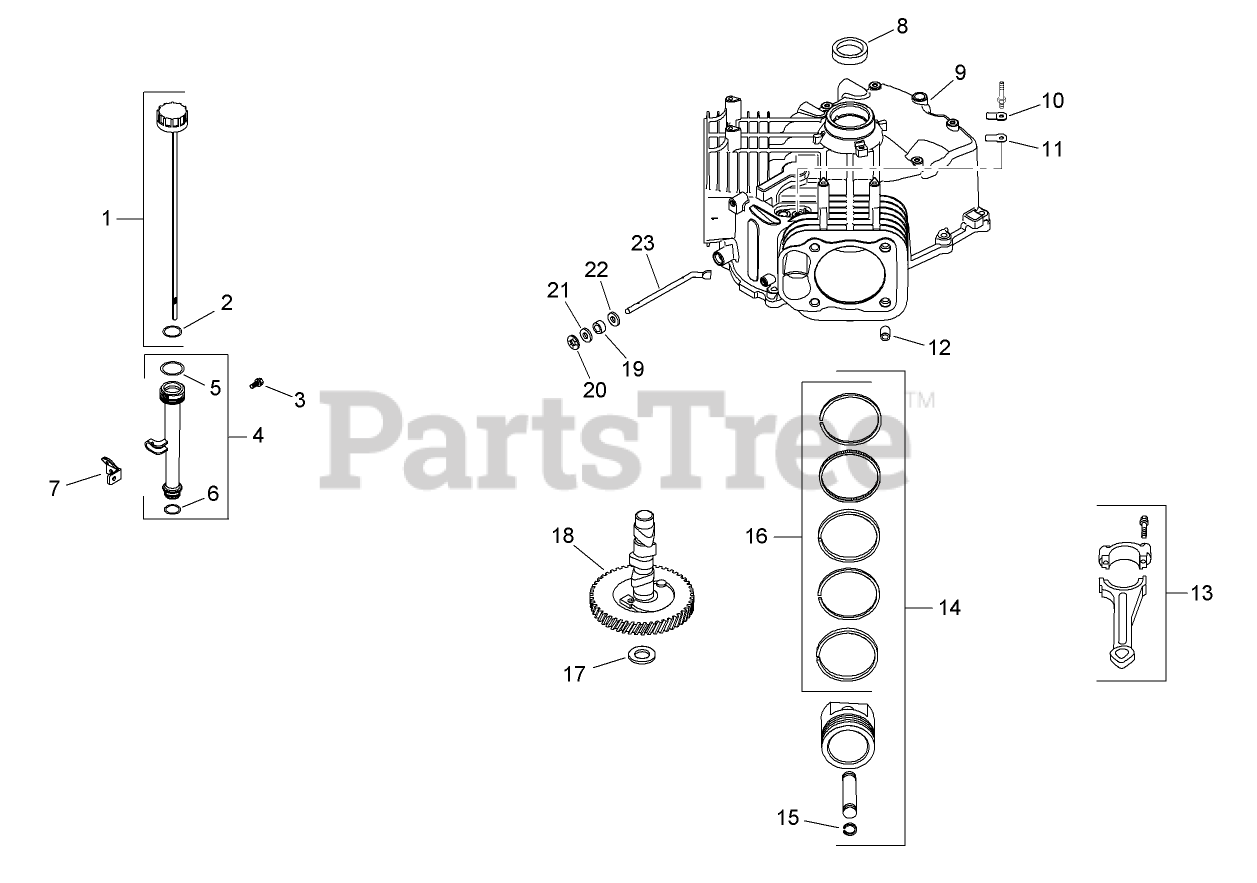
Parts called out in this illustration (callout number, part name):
1	Dipstick Kit (Includes?2)
2	O RING-DIPSTICK
3	SCREW-FLG, THD FRM (M5X0.8X13)
4	OIL FILL TUBE KIT
5	O-Ring
6	O-RING
7	BRACKET-TUBE, OIL FILL
8	SEAL-OIL
9	SHORTBLOCK (SV710-740)
10	RETAINER-REED, BREATHER
11	REED-BREATHER
12	PIN-LOCATING
13	ROD-CONNECTING (STD)
14	PISTON W/RING SET (STD) (INCLUDES REF 8, 17)
14	PISTON W/RING SET (.25)
14	PISTON W/RING SET (.08) (USE 25 874 02-S KIT)
15	RETAINER-PIN, PISTON
16	PISTON RING SET (STD)
16	PISTON RING SET (.25)
17	SHIM-CAMSHAFT (WHITE .028)
17	SHIM-CAMSHAFT (BLUE .03)
17	SHIM-CAMSHAFT (RED .032)
17	SHIM-CAMSHAFT (YELLOW .034)
17	SHIM-CAMSHAFT (GREEN .036)
17	SHIM-CAMSHAFT (GRAY .038)
17	SHIM-CAMSHAFT (BLACK .04)
18	CAMSHAFT KIT (INCLUDES 25 357 14-S)
19	SEAL-CROSS SHAFT, GOVERNOR
20	RETAINER-RING
21	WASHER-FLAT (9MM)
22	WASHER-FLAT (11/32)
23	SHAFT-CROSS, GOVERNOR
